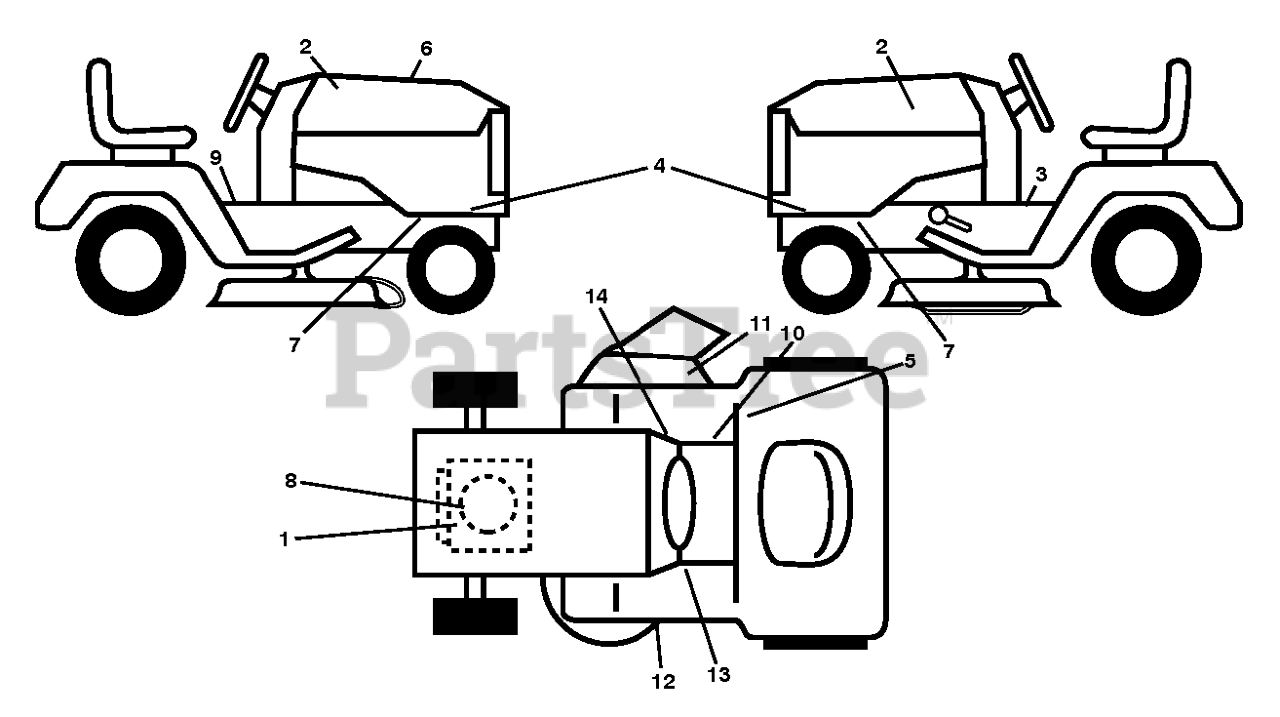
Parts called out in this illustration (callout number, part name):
1	DECAL
2	DECAL.BADGE.170MM.TEXTLOGO.
3	LABEL
5	Decal, Fender 100 DB/CE
8	DECAL
9	DECAL BTRY SYMBOLS
10	DECAL
11	DECAL.WARN.DFLECT/CTFINGR.SRD
12	Decal, Mower V-Belt Schematic
13	DECAL
14	DECAL PARK BRAKE
